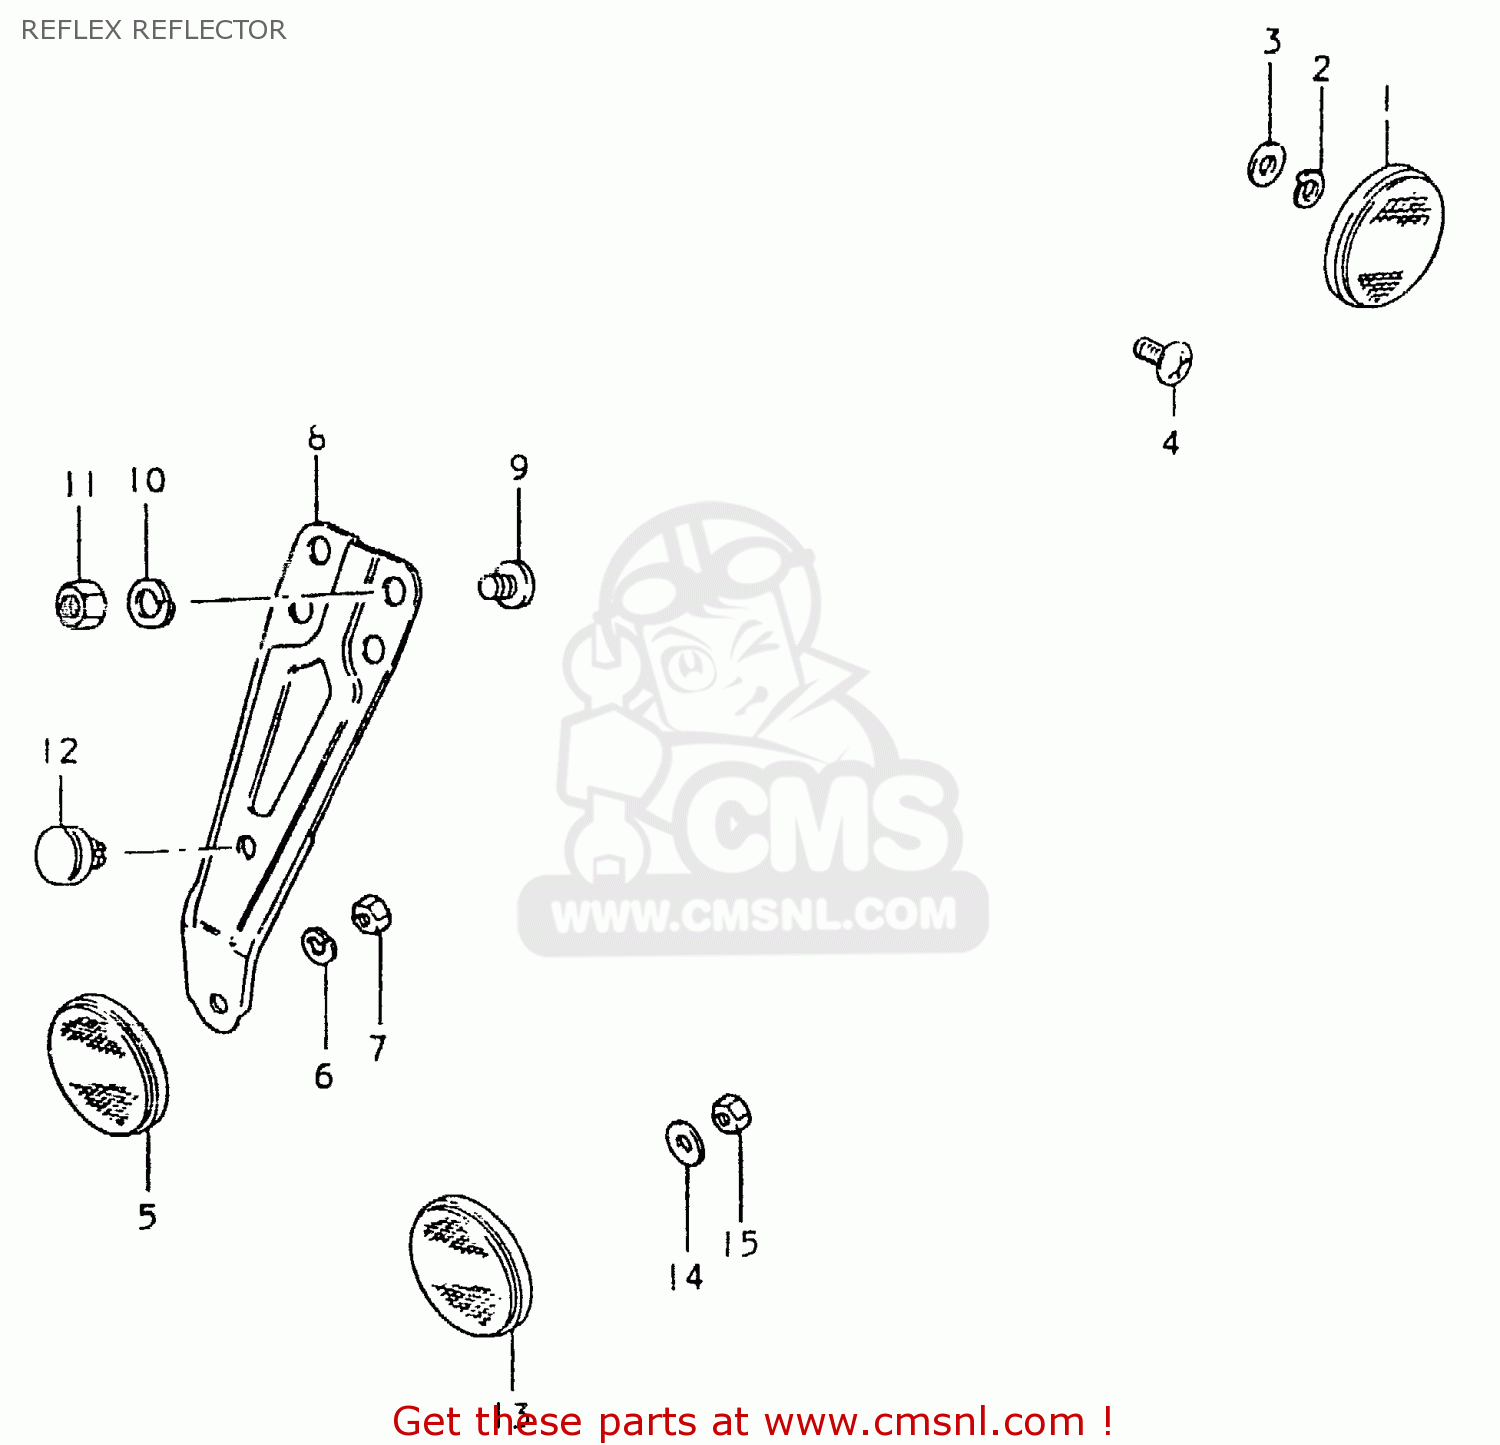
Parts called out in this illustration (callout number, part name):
1	REFLEX REFLECTOR,FR
2	LOCK WASHER
3	WASHER
4	SCREW 5X6
5	REFLEX REFLECTOR,RR
6	WASHER
7	NUT
8	BRACKET
9	SCREW
10	LOCK WASHER
11	NUT
12	CUSHION
13	REFLECTOR,REFLEX
14	WASHER
15	NUT
